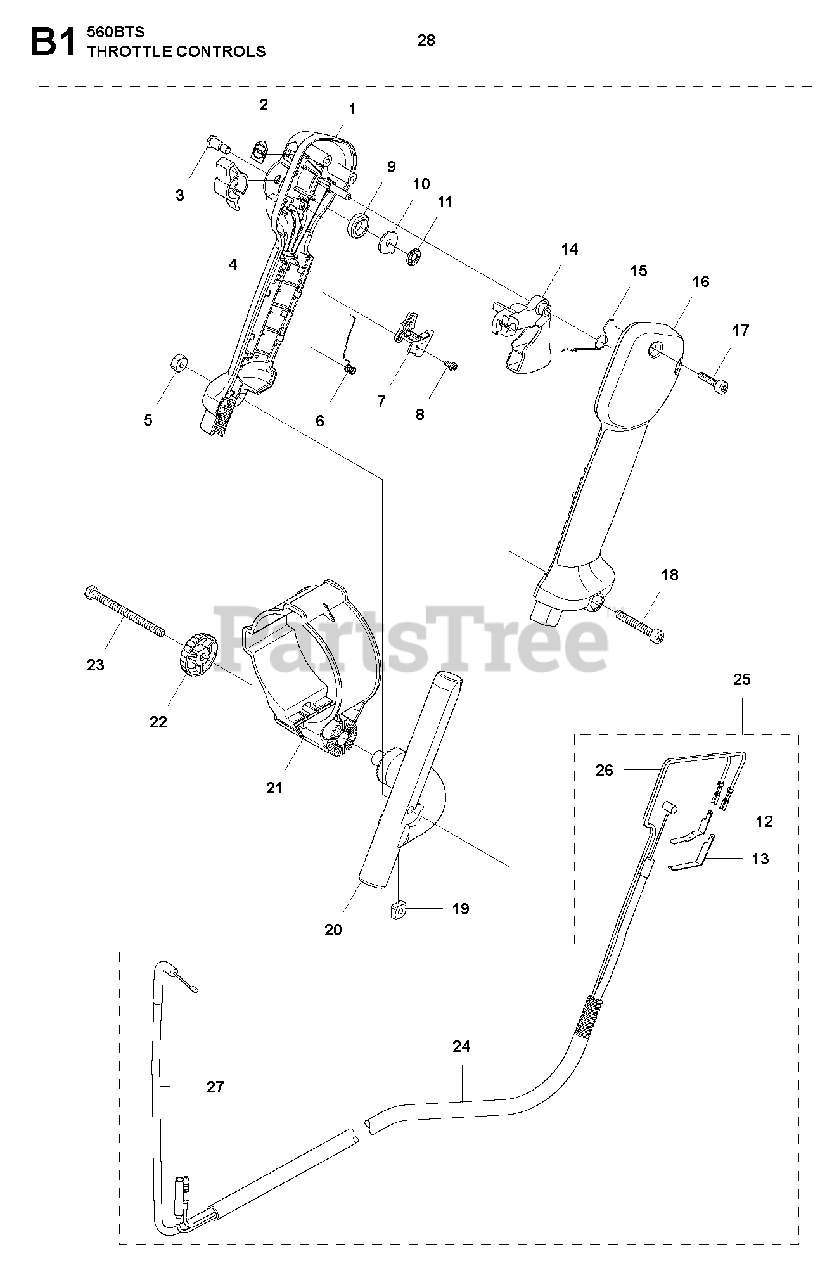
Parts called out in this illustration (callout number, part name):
1	HANDLE HALF (L)
2	PLATE
3	SHAFT PIVOT
4	LEVER STOP
5	NUT
6	SPRING
7	RETAINER
8	SCREW
9	SPRING RUBBER
10	WASHER
11	CLIP
12	CONTACT SPRING
13	CONTACT SPRING
14	TRIGGER 848L5W34C0
15	SPRING
16	HANDLE HALF (R)
17	SCREW
18	SCREW
19	SQUARE NUT M5
20	HOLDER, HANDLE
21	HANDLE HOLDER
22	KNOB
23	SCREW
24	TUBE
25	WIRING ASSY
26	CORD COMPLETE
27	CABLE, COMP
